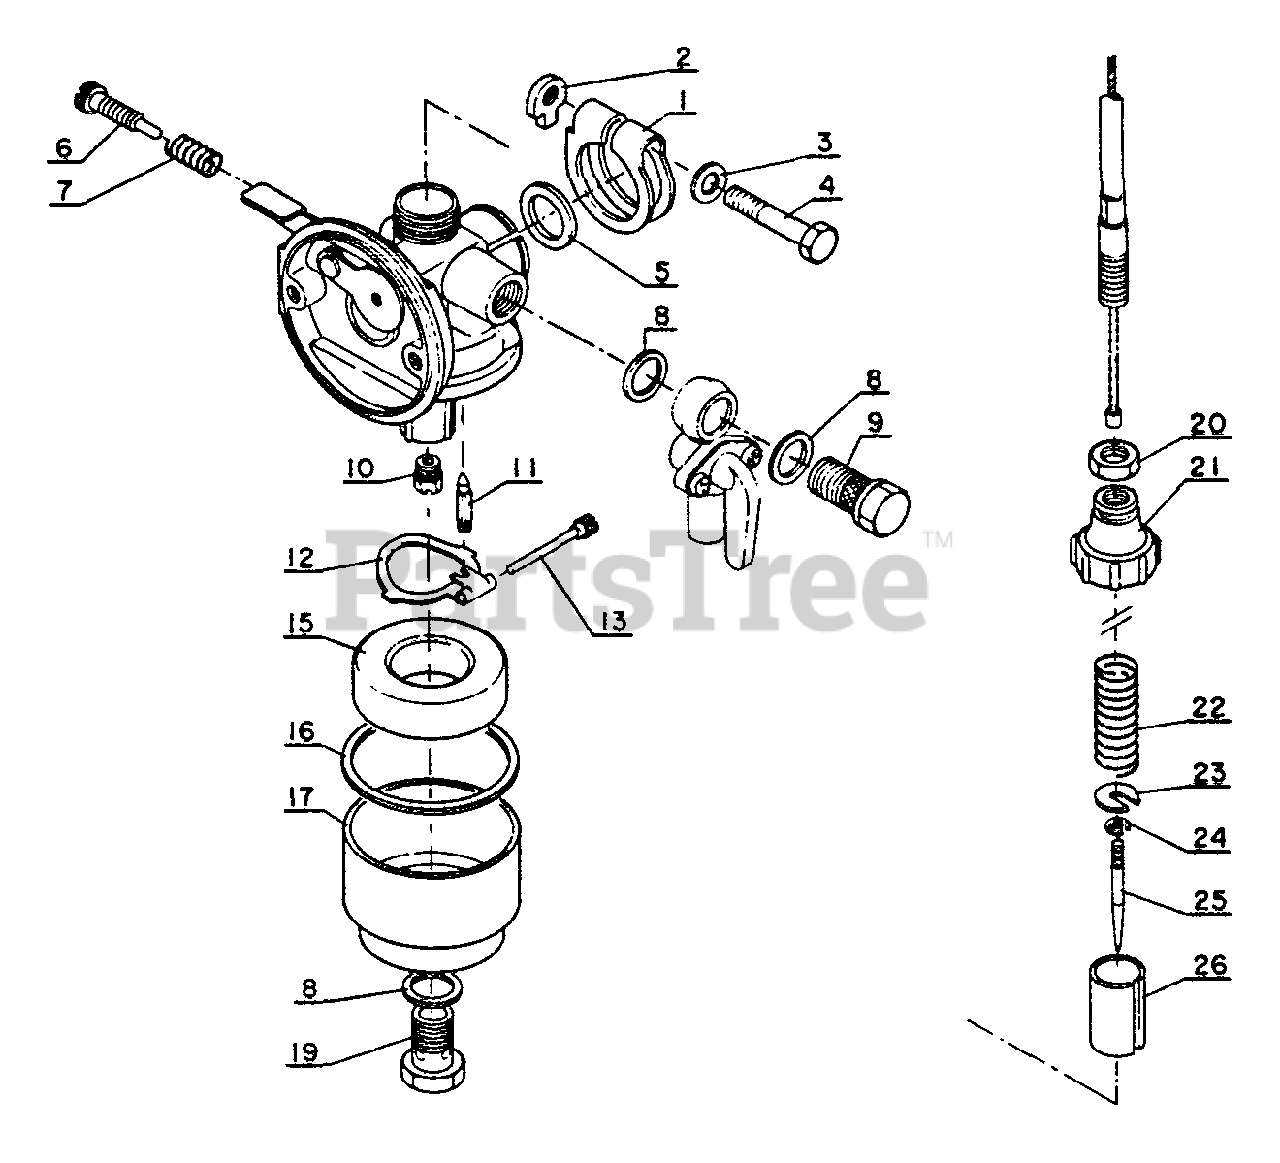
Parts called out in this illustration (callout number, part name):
1	CARBURETOR
1	NUT
2	CLIP
3	WASHER
4	BOLT
6	SCREW, IDLE ADJUST
7	SPRING, IDLE ADJUST
9	BOLT, BANJO
10	JET, MAIN
11	VALVE, INLET NEEDLE
12	LEVER, METERING
13	PIN, METERING LEVER
15	FLOAT
16	GASKET, FLOAT CHAMBER
17	CHAMBER, FLOAT
19	BOLT
20	NUT
21	COVER - TOP
22	SPRING, THROTTLE
23	SEAT, SPRING
24	RING, RETAINING
25	NEEDLE, JET
26	VALVE, THROTTLE
